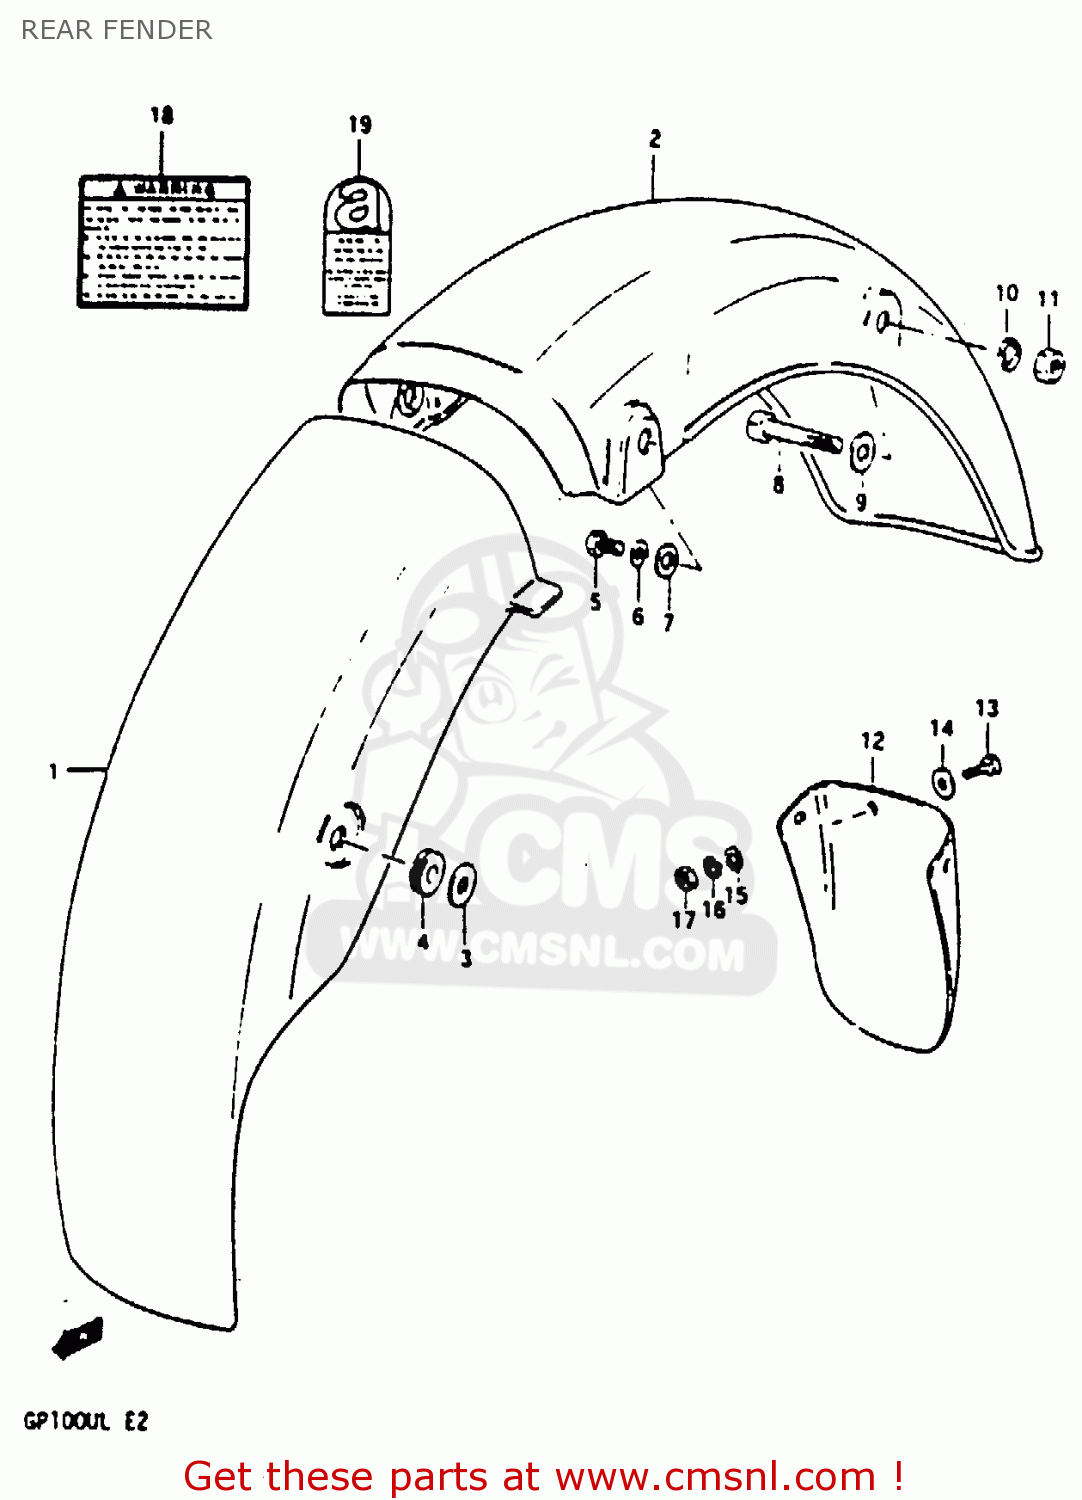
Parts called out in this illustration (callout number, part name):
1	BODY,RR FENDER FR
2	BODY,RR FENDER RR
3	WASHER
4	CUSHION
5	BOLT
6	WASHER,LOCK
7	WASHER
8	BOLT 8X45
9	WASHER
10	LOCK WASHER
11	NUT
12	FLAP,RR FENDER MUD
13	BOLT
14	WASHER
15	WASHER
16	WASHER,LOCK
17	NUT 6MM
18	LABEL
19	LABEL,ASBESTOS WARNING
